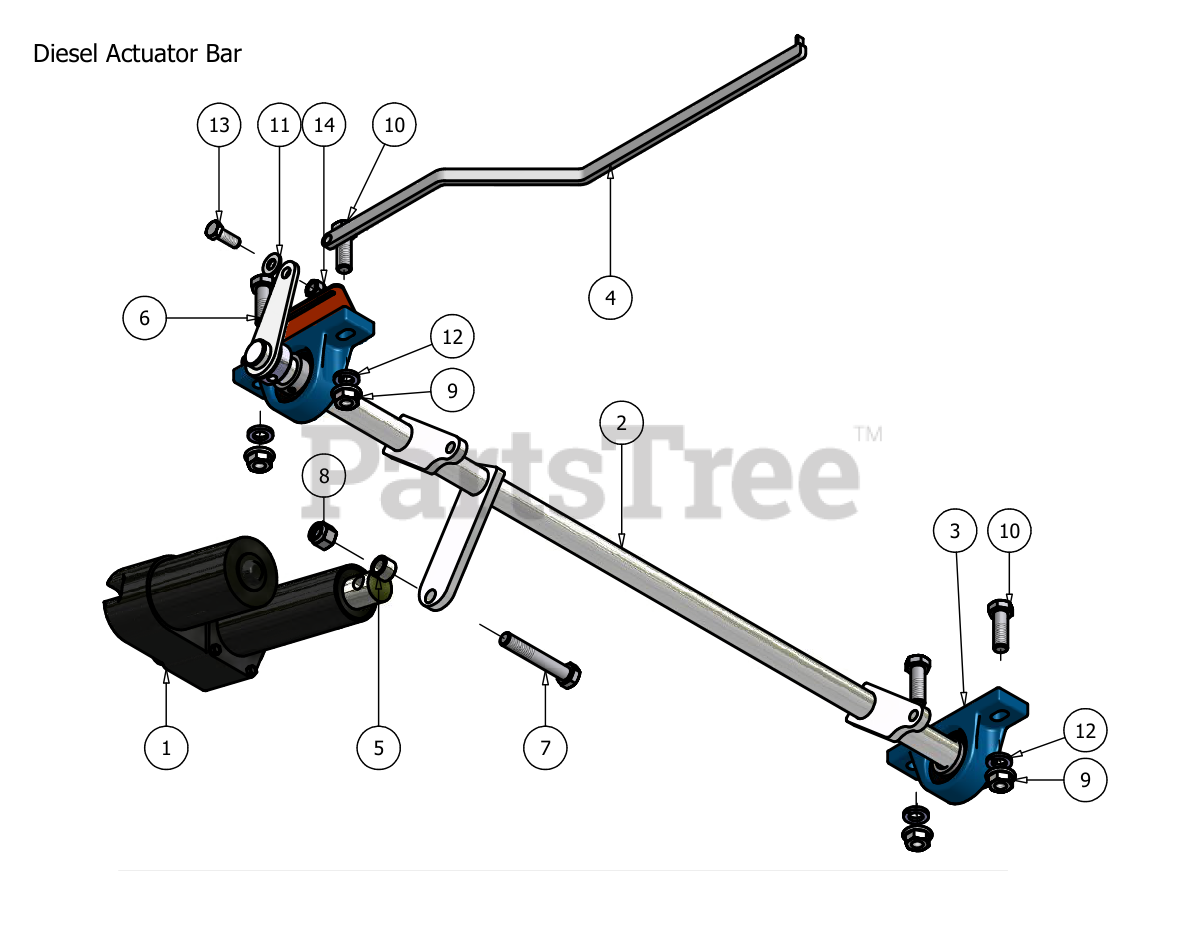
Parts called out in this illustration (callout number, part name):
2	Actuator Bar
3	1" Pillow Block
4	Height Indicator
5	1/2" Washer
6	2006 Height Indicator Lever
7	1/2" x 2 1/2" Hex Bolt
8	1/2" Nylock Nut
9	1/2" Flange Nut
10	1/2" x 1 1/2" Hex Bolt
11	.360 ID Plastic Washer
12	1/2" Lock Washer
13	3/8" x 1" Hex Bolt
14	3/8 Nylock Nut
